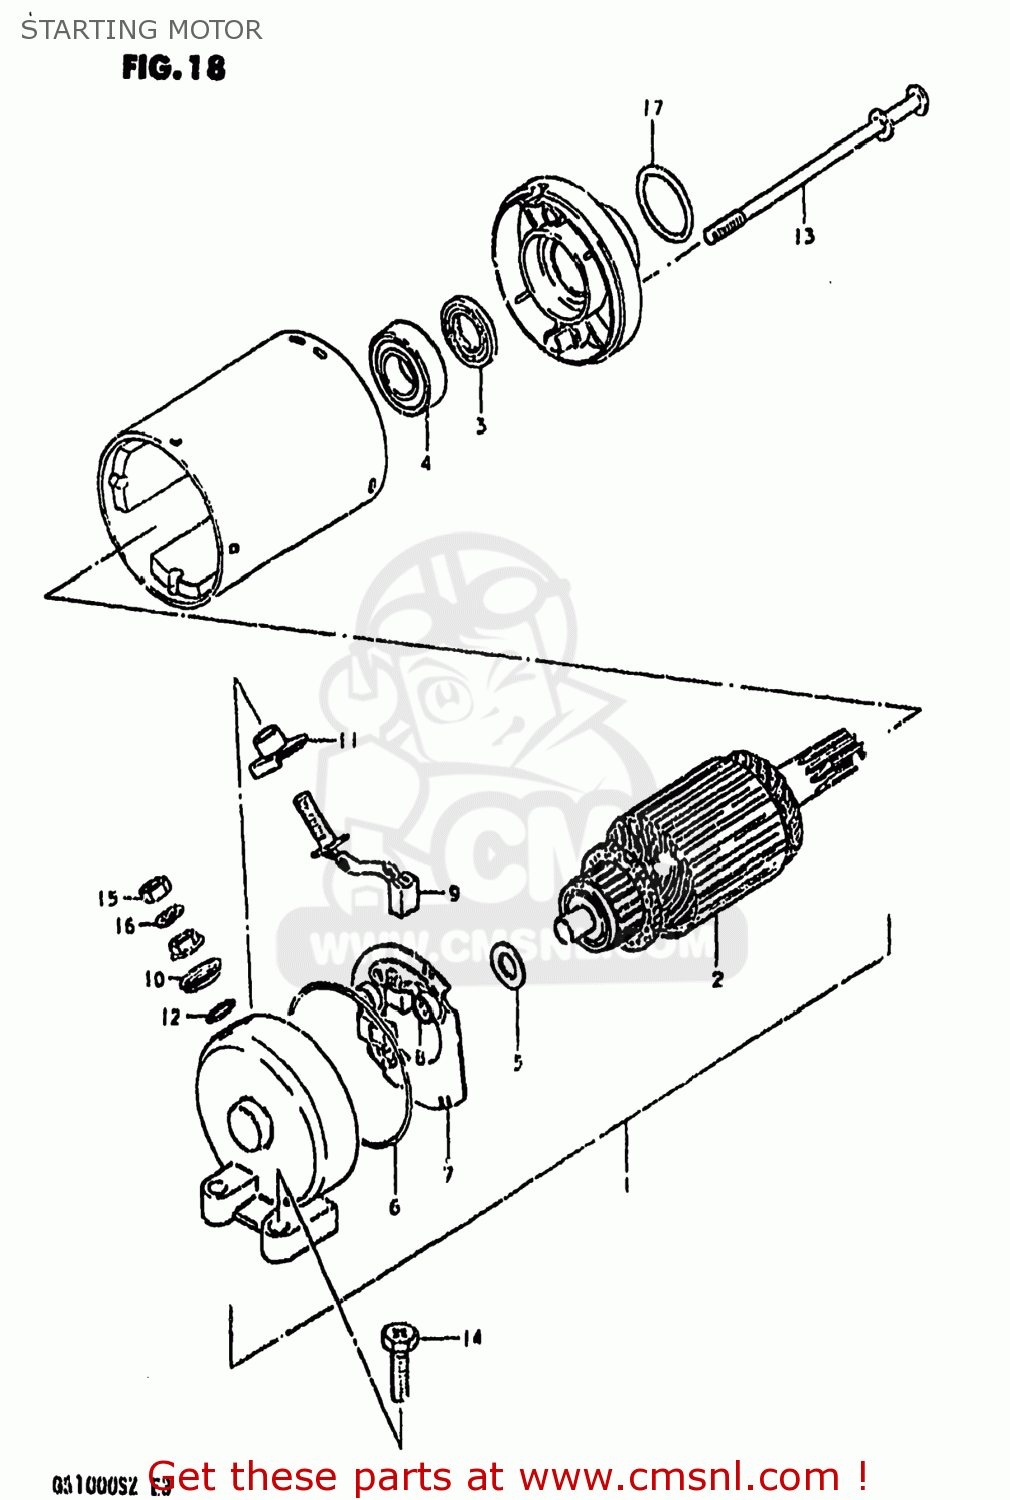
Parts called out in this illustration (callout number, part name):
1	MOTOR ASSEMBLY,STARTING
2	ARMATURE
3	SEAL,OIL
4	BEARING
5	SHIM,ARMATURE
6	O RING
7	HOLDER,BRUSH
8	SPRING
9	BRUSH (+)
10	BUSHING (1)
11	BUSH,NO.2
12	O-RING
13	BOLT,STARTING MOTOR HOUSING
14	SCREW (6X25)
15	NUT 6MM
16	LOCK WASHER
17	O RING(D:2,ID:24.5)
